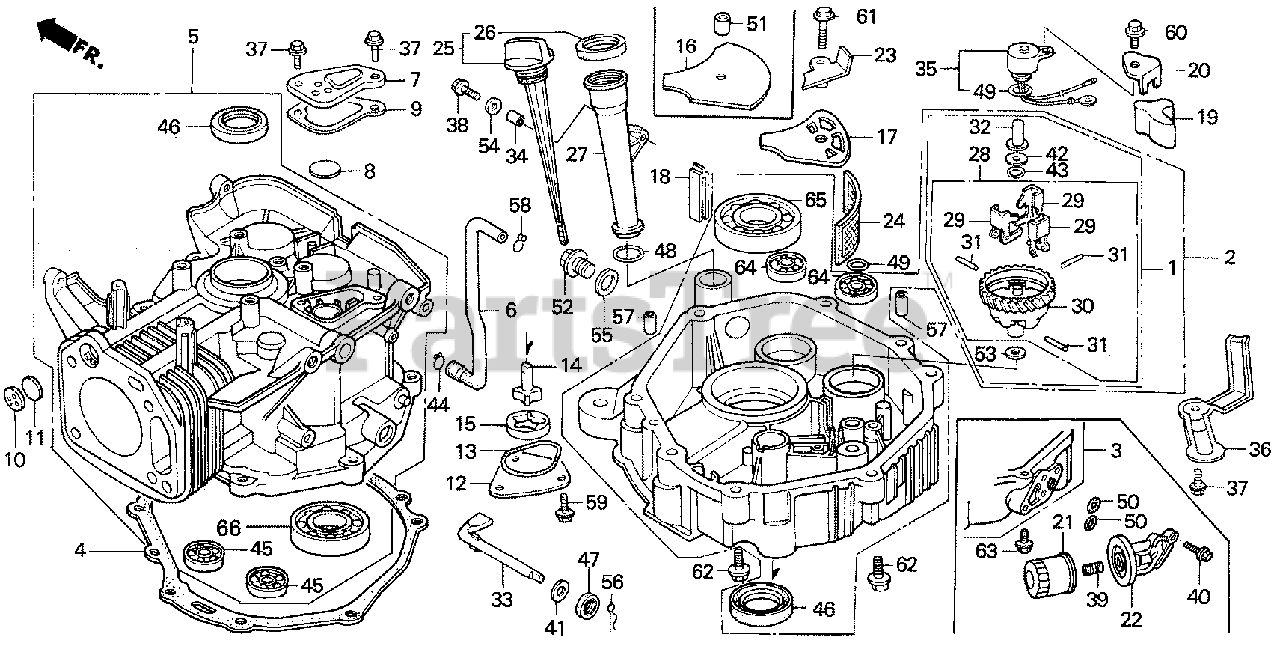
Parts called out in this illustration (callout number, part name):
1	GOVERNOR KIT
3	PAN ASSY., OIL
4	GASKET, OIL PAN
5	CYLINDER ASSY.
6	TUBE, BREATHER
7	CAP, BREATHER CHAMBER
8	VALVE, BREATHER
9	GASKET, BREATHER CAP
12	COVER, OIL PUMP
13	O-RING, PUMP COVER
14	ROTOR (INNER)
15	ROTOR, OIL PUMP (OUTER)
16	PLATE, OIL FILTER
18	RUBBER, OIL RETURN
21	FILTER, OIL (TOYO) (Honda Code 3179553). (SOLD IN MULTIPLES OF 30)
21	FILTER, OIL (FILTECH INC.) (Honda Code 3630399). (SOLD IN MULTIPLES OF 30)
21	FILTER, OIL (Honda Code 6424329). (SOLD INDIVIDUALLY)
21	FILTER, OIL (Honda Code 6836290). (SOLD INDIVIDUALLY)
21	FILTER, OIL (Honda Code 5159298). (SOLD INDIVIDUALLY)
22	BASE, OIL FILTER
24	SCREEN, OIL FILTER
25	CAP ASSY., OIL FILLER
26	GASKET, OIL FILLER CAP
27	EXTENSION, OIL FILLER
28	GOVERNOR ASSY.
29	WEIGHT, GOVERNOR
30	HOLDER, GOVERNOR WEIGHT
31	PIN, GOVERNOR WEIGHT
32	SLIDER, GOVERNOR
33	SHAFT, GOVERNOR ARM
34	COLLAR, EXTENSION
37	BOLT, FLANGE (6X12) (CT200)
38	BOLT, FLANGE (6X35)
39	HOLDER, OIL FILTER
40	BOLT, FLANGE (6X25)
41	WASHER, THRUST (8.1MM)
43	CLIP, GOVERNOR HOLDER
45	BEARING, RADIAL BALL (6202)
46	OIL SEAL (35X52X8)
47	OIL SEAL (8X14X5)
48	O-RING (22.5X2.2)
49	O-RING (11.8X2.4)
50	O-RING (11X1.9) (NOK)
51	COLLAR, OIL FILTER SETTING
52	BOLT, DRAIN PLUG (20MM)
53	WASHER, PLAIN (6MM)
54	WASHER, PLAIN (6MM)
55	WASHER, DRAIN PLUG (20MM)
56	PIN, LOCK (8MM)
56	PIN, LOCK (10MM)
57	PIN, DOWEL (8X12)
58	CLIP, TUBE (C11)
59	BOLT, FLANGE (6X12)
61	BOLT, FLANGE (6X25)
62	BOLT, FLANGE (8X40)
63	BOLT, FLANGE (8X60)
64	BEARING, RADIAL BALL (6202)
65	BEARING, RADIAL BALL (6207)
66	BEARING, RADIAL BALL (6207)
